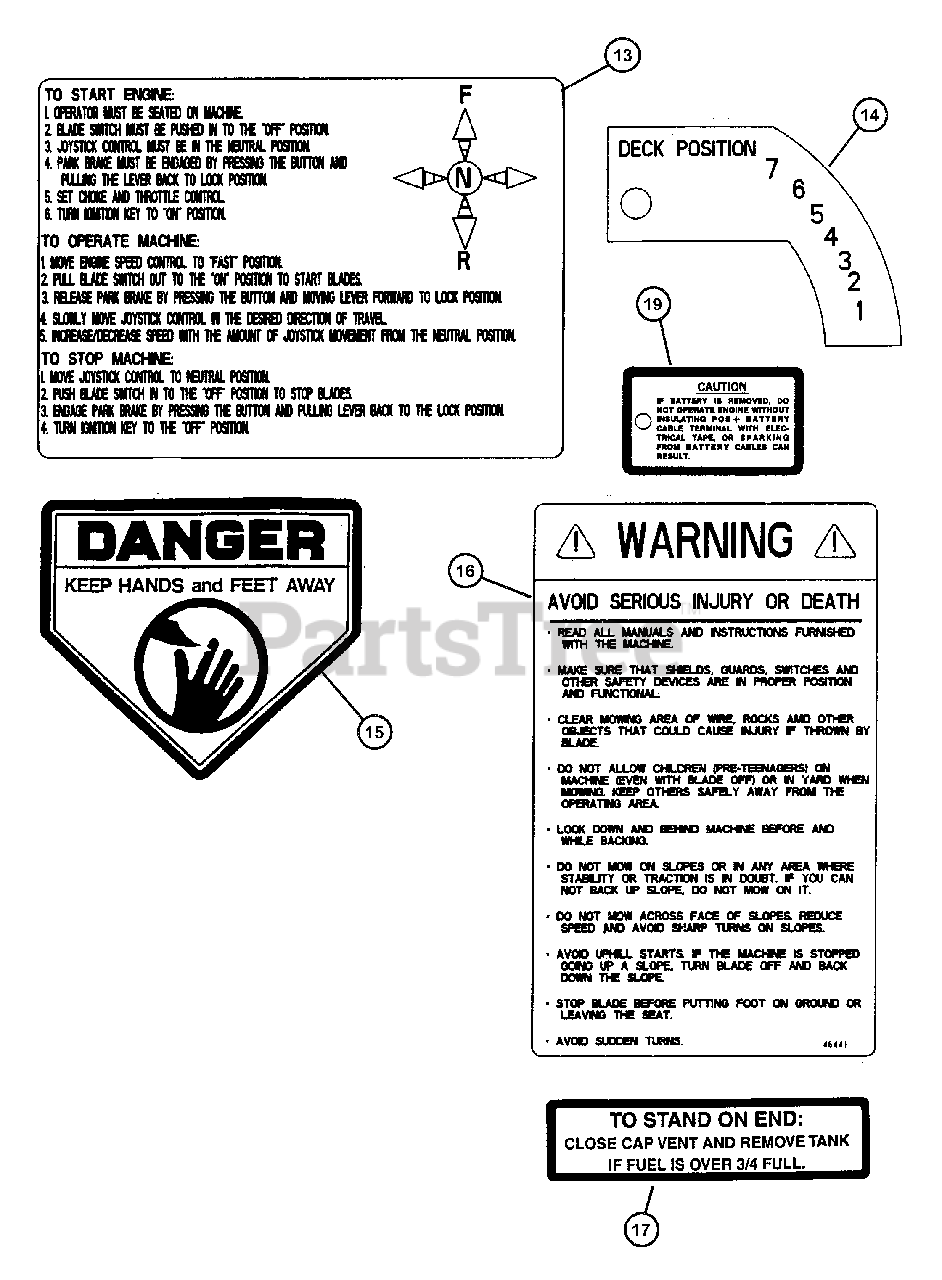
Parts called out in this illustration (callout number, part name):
13	DECAL, Operation
14	DECAL, Deck Position
15	DECAL, CPSC
16	DECAL, Safety Instruction
17	DECAL, Caution Fuel
19	DECAL, Caution Tag
